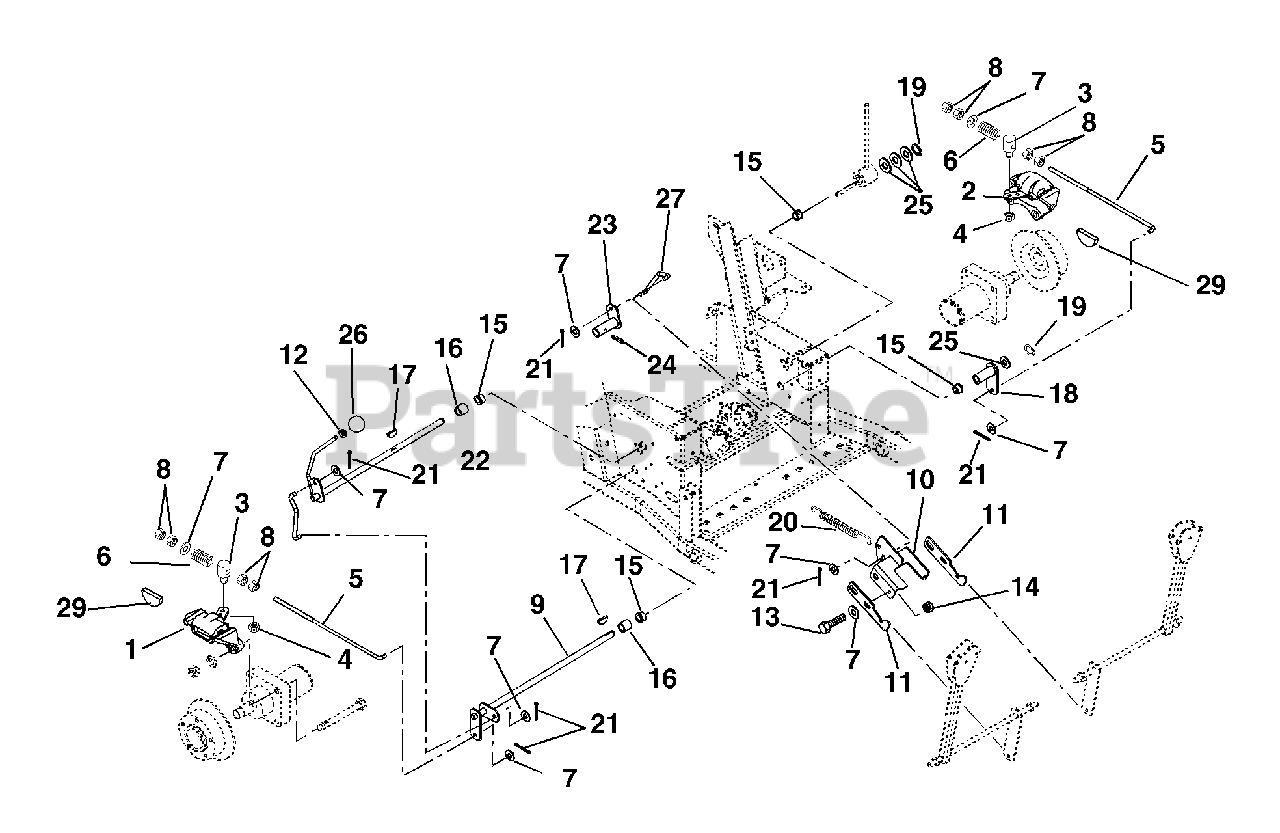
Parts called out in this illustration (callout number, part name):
1	Caliper, Park Brake (CW) Right Hand
2	Caliper, Park Brake (CCW) Left Hand
3	Pivot-Brake Rod
4	Nut-Locking-Center .31-18
5	Rod-Brake 12 inch
6	Spring-Compression .143 x .710 x 2.00
7	Washer-Flat-Steel .406 x .812 x .065
8	Nut-Hex .38-16
9	Shaft-Brake Cross
10	Interlock-Fixed
11	Interlock-Adjustable
12	Nut-Hex-Jam .375 -16
13	Bolt-Hex .38-16 x 1.00 Grade 5
14	Nut-Locking-Center .38-16
15	Bushing-Flange .630 x 1.000 x .625
16	Spacer .630 x .878 x 1.000
17	Key-Woodruff .19 x .75 Hard #9
18	Arm-Brake Left-Hand
19	Ring-Retaining-External .625 x .050
20	Spring-Tension .105 x .85 x 5.00
21	Pin-Cotter External .09 x .75
22	Shaft-Brake Actuating
23	Actuator
24	Pin-Roll .125 x 1.00
25	Washer-Flat-Steel .627 x .990 x .032
26	Knob-Steering Lock
27	Rod-Brake Actuating
28	Pin-Cotter-External .09 x .75 r
29	Pad, Disk Brake
